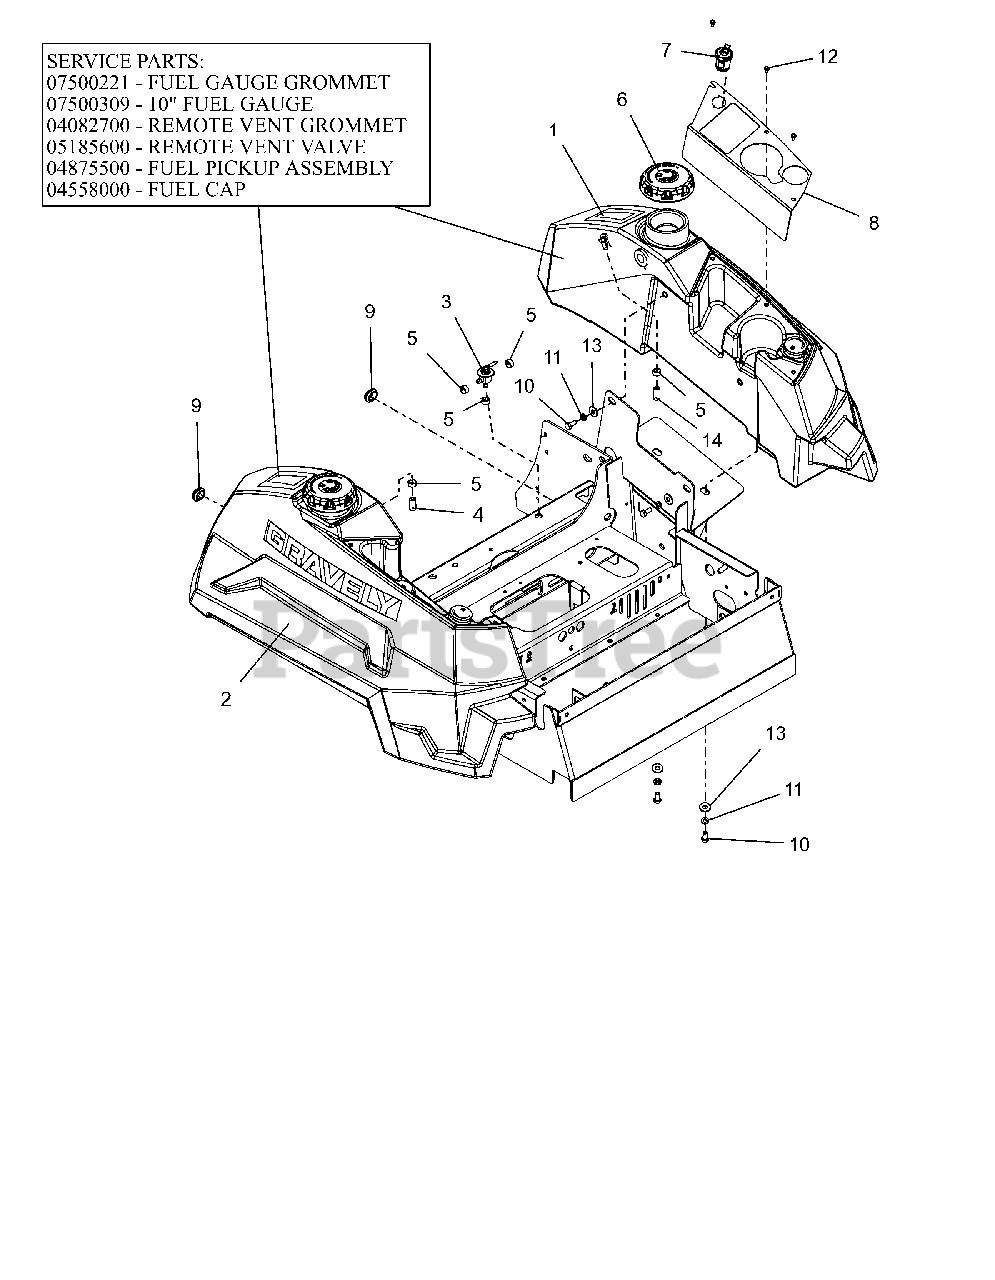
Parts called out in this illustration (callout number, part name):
1	ASM, PT200/400 LH FUEL TANK
2	ASM, PT200/400 RH FUEL TANK
2	GROMMET, FUEL GAUGE
2	GAUGE, REMOTE FUEL SEALED 10"
2	GROMMET, REMOTE VENT NITRILE
2	VALVE, COMBINATION VENT 3/16
2	ASSM,LRG TANK FUEL PICKUP LINE
2	CAP, FUEL VENTIN AUTOLOCK
3	VALVE - FUEL
4	HOSE, .25 LOW-PERM BULK GAS
5	CLAMP, FUEL LINE
6	CAP, FUEL NONVENT AUTOLOCK
7	PORT, 12 VOLT POWER
8	CUP HOLDER/POCKET PLATE - RED
9	GROMMET,RUBBER 5/8 ID/1.13 OD
10	@BLT-HEX .31-18X.75 GR5 YWZC
11	@WSHR-LK .31X.078 REG YWZC
12	SCR-MCH 10-24X.38 HWHSTAINLESS
13	@WSHR-FL-STL.38X.875X.083 YWZC
14	HOSE, .25 LOW-PERM BULK GAS
